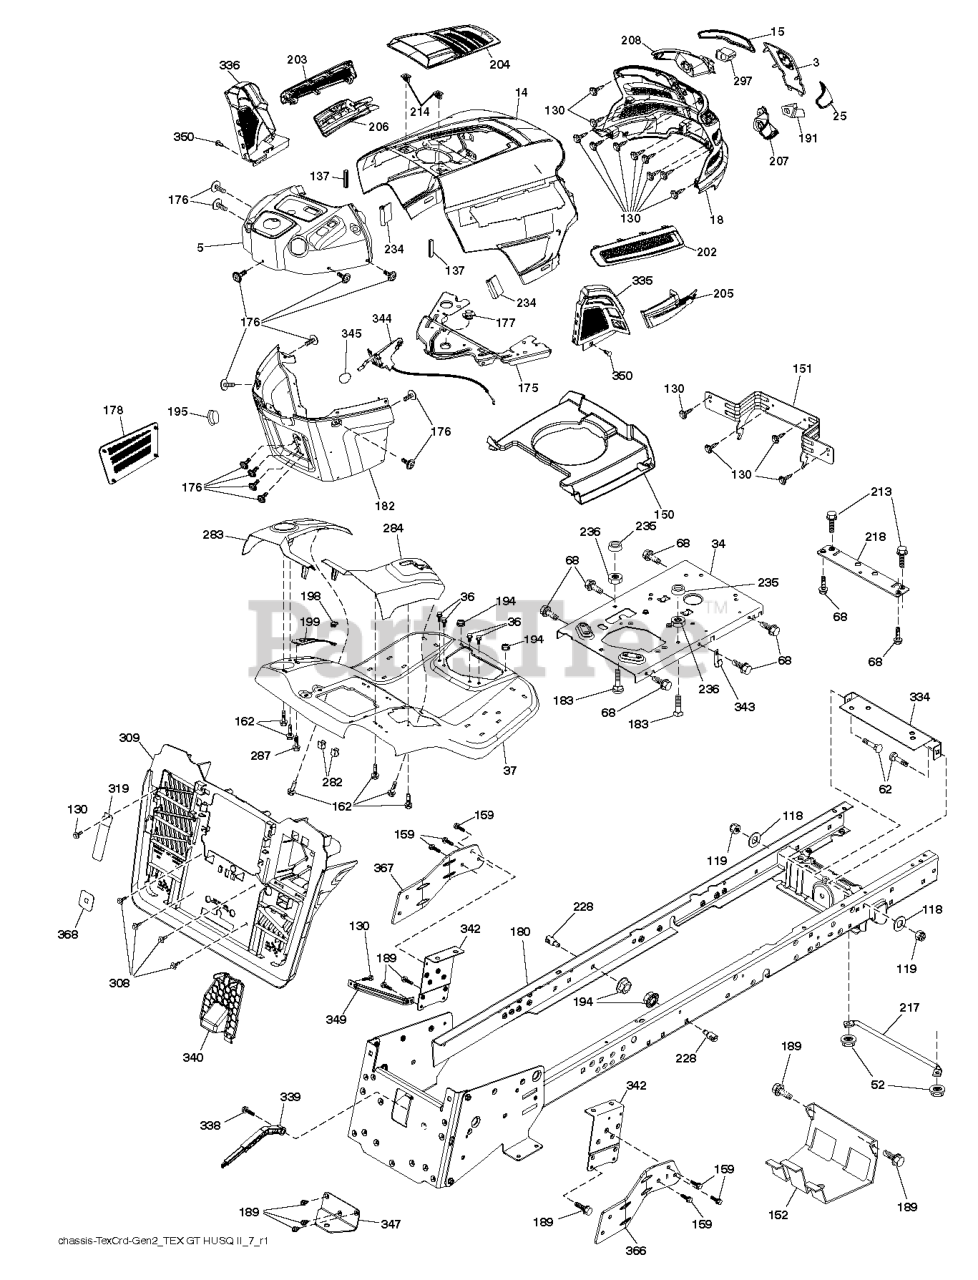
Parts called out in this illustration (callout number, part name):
3	APPLIQUE.SUBASM.GT.HUSQ.II
14	HOOD.ASM.HUSQVARNA.GT.TEX.ORAN
15	LENS.HEADLIGHT.LH.GTII.2011
18	GRILLE.SUBSTRATE.2011.
25	LENS.HEADLIGHT.RH.GTII.2011
34	PLATE.ENGINE.WELDED.CHASSIS
36	SCREW 5/16"
37	FENDER.TEX.SRD.CRD.FRN.GUARDS
52	LOCKNUT
62	BOLT D
68	Screw 5/16-18 x 1/2 Hex, Self Tapping 5/16-18 x 1/2
118	WASHER
130	SCREW.#10 X 0.750.BOS
137	BUMPER DASH
150	AIR DUCT.GTV2(1.66"RING HEIGHT
151	BRACKET.PIVOT.HOOD.GT.HUSQ.II
152	SHIELD.BROWNING.PNT.GT.V2
159	SCREW, 3/8-16X3/4
162	SCREW.HI-LO.CONSOLE
175	PLATE.CROSSMEMBER.HUSQ
176	SCREW.#10-24X5/8.RN.QU
177	BUSHING, STEERING
178	CARGO.ASM.NET.TXGT.W/C
180	WELDMENT.CHASSIS.TEX.CRD.GEN.2
182	DASH DASH LOWER
183	BOLT.5/16-18X1-1/4 FULL THD
189	SCREW
191	INSERT.REFLECTIVE.RH.HUSQ.GTII
194	NUT LOCK HEX FLANGE 5/16-18
195	PLUG.HOLE.DASH.LOWER.12V.BLK
198	INDICATOR.DECK.LIFT.RED
199	PLATE DECK LIFT
202	VENT.SIDE.RH.GT.HUSQ.II.
203	VENT.SIDE.LH.GT.HUSQ.II.498
204	VENT.TOP.EXTERNAL.FILL.GT2.GRE
205	SIDE.TRIM.RH.GT.HUSQ.II
206	SIDE.TRIM.LH.GT.HUSQ.II.GRAY
207	BEZEL LIGHT.RH.GT.II.MYLAR
208	BEZEL LIGHT.LH.GT.II.MYLAR
213	BOLT
214	CLIP.RETAINER.TINNER.
217	ROD.PIVOT.HOOD
218	X-PIECE.HOOD.STOP.NON/
228	STUD.FASTNER.W/ANTI-ROTATE
234	BUMPER.HOOD.TEX.HUSQVARNA
235	SPACER FENDER
236	NUT.CENTERLOCK.5/16-
282	CLIP.RETAINER.CONSOLE.LT.HUSQ
283	CONSOLE.DECKLIFT.CRDII.498
284	CONSOLE.PEDAL.HYDRO
287	SCREW 1/4X20
297	INSERT.REFLECTIVE.LH.HUSQ.GTII
308	BOLT.5/16-18UNCX3/4 W/SEMS.BLK
309	BACKPLATE.ASM.CRDII.ANTIROTAT
319	LEVER.BAG.CRDII.ANTIROTATION
334	BRACKET.ENGINE
335	COVER.LOWER.DASH.RH.BLACK
336	COVER-LH.LOWER.DASH.GT2.BLACK
338	BOLT BOLT SHOULDER
339	LEVER LEVER BAGGER
340	BATTERY.DOOR.TEX.CRD.GEN.2,1
342	SUPPORT SUPPORT FENDER
343	CLIP CLIP
344	CONTROL.EZ.MULCH.TEX/CRD
345	RP KNOB.OVAL.TAPERED.3/8-16BLK
347	HITCH TOW
349	BRACKET.SUPPORT.LRVB/CRD
350	CLIP.X-MAS.TREE
366	BRACKET.RH.FRONT.BAGGER.BLACK
367	BRACKET.LH.FRONT.BAGGER.BLACK
368	FULL.LEVER.BAGGER.TEX.CRD
